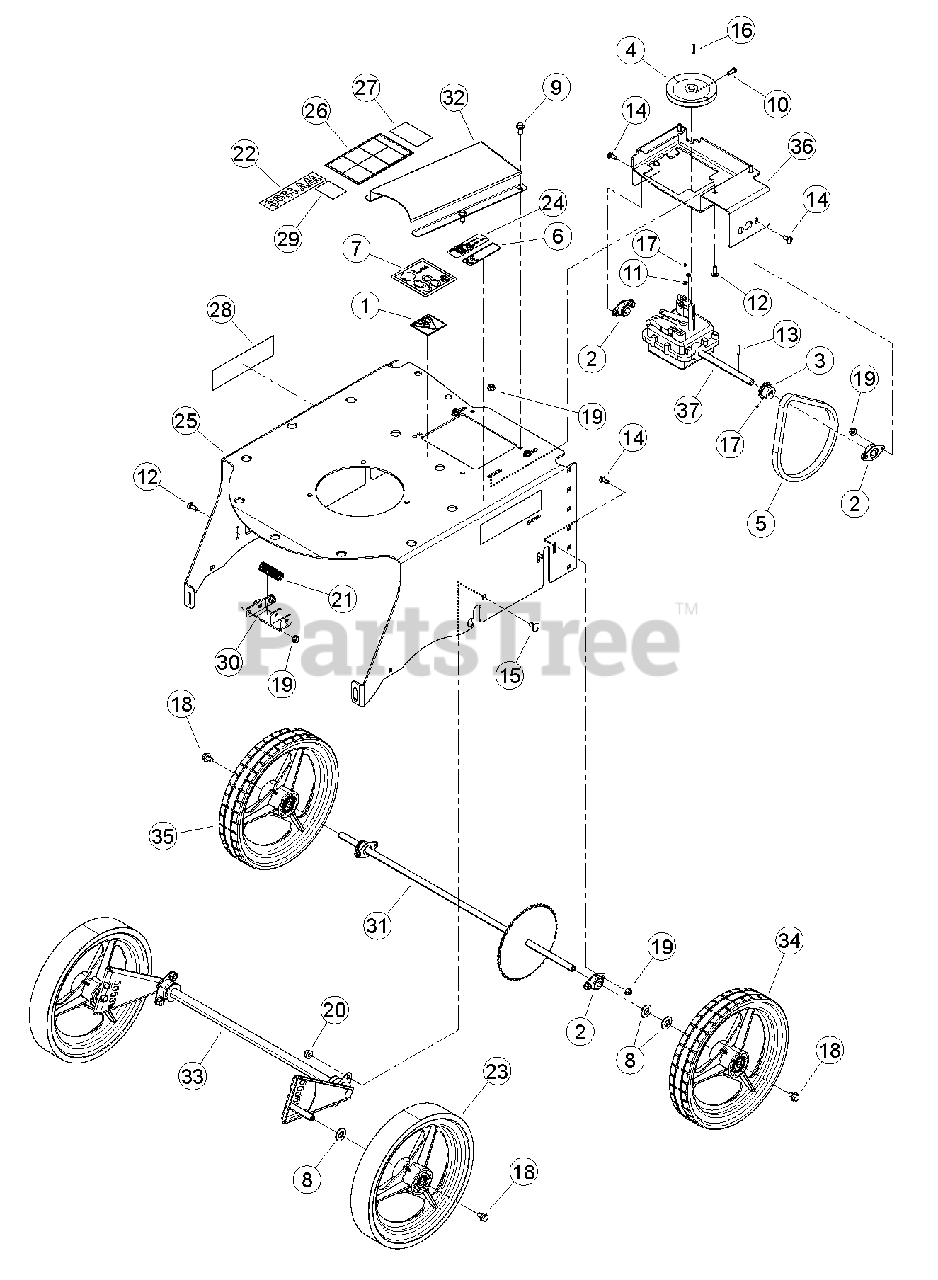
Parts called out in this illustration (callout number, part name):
1	DECAL, SHIELD DANGER ISO
2	BEARING, 1/2 FLANGE
3	SPROCKET, BEARVAC 35B10
4	PULLEY, 4 O.D. X 12MM BORE
5	CHAIN, #35 X 62 PITCH W/ CONN. LINK
6	DECAL, 6HP SP BEARVAC INFORMATION (WV190S ONLY)
7	DECAL, 98 DB (WV190S ONLY)
8	WASHER, 1/2 SAE FLAT
9	SCREW, 11/32-12 X 7/8 HWH T-AB
10	SET SCREW, 1/4 X 5/8 SQ HD
11	WASHER, #8 SAE
12	BOLT, 1/4 X 3/4 GR5 CRG ZP
13	PIN, 1/8 X 7/8" SPRING
14	BOLT, 1/4 X 5/8 GR5 CRG NC ZP
15	BOLT, 5/16 X 5/8 GR5 CRG ZP
16	KEY, 4MM SQ X 20 MM
17	SCREW, #8-32 X 3/16 KNR CUP PT
18	BOLT, 5/16-18 X 1/2 G5 HH SR/FLN
19	NUT, 1/4-20 NYLOCK-FLANGE
20	NUT, 5/16-18 NYLOCK-FLANGE
21	SPRING, LC-072J06S COMPRESSION
22	DECAL, MODEL WV190S
22	DECAL, MODEL WV160S
23	ASSEMBLY, WHEEL BEARVAC PUSH
24	DECAL, ATLANTIC BRIDGE LTD INFO (WV190S ONLY)
25	ASSEMBLY, SELF VAC HOUSING W/ DECALS
26	DECAL, OPERATING INSTRUCTIONS ISO
27	DECAL, DANGER
28	DECAL, ECHO BEARCAT 6.82 X 1.90
29	DECAL, ECHO BEARCAT QR CODE
30	WELDMENT, BEARVAC HEIGHT ADJ.
31	WELDMENT, SP LONG AXLE
32	GUARD, BEARVAC BELT
33	WELDMENT, AXLE PIVOT
34	WHEEL, BEARVAC SP LEFT
35	WHEEL, BEARVAC SP RIGHT
36	WELDMENT, TRANSMISSION MOUNT
37	TRANSMISSION, 3 SP. BEARVAC
